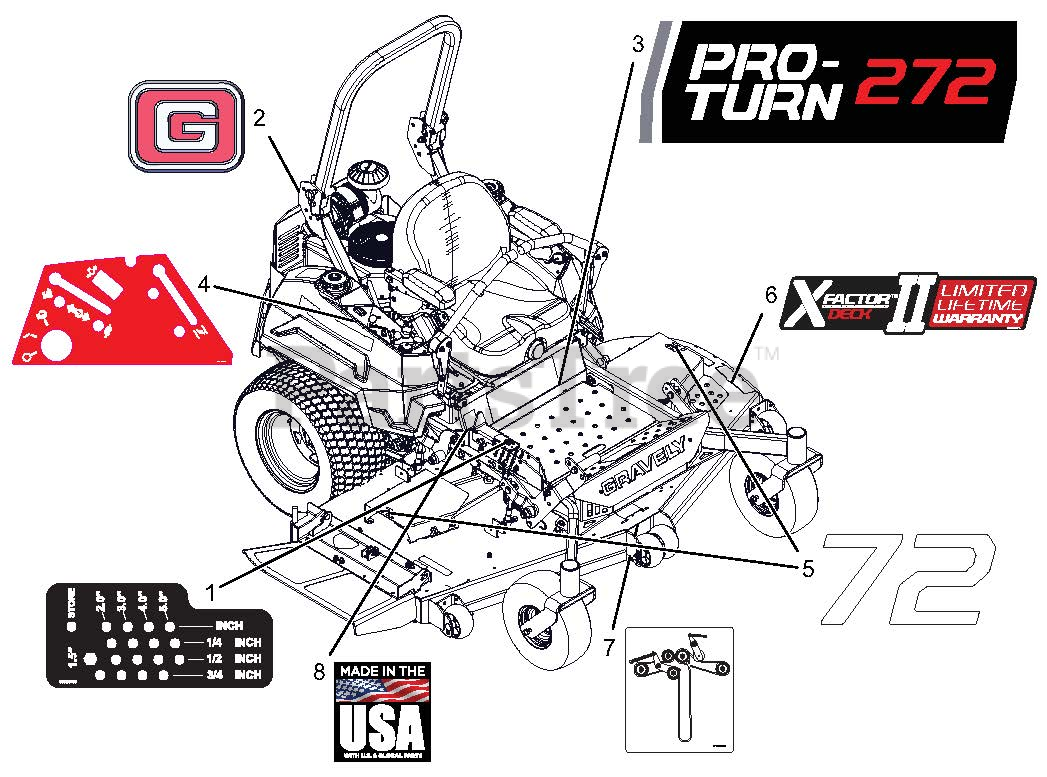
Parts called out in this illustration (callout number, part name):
1	DECAL, HEIGHT OF CUT
2	DECAL, GRAVELY BRAND
3	DECAL, PRO-TURN 272
4	DECAL, NON-EFI CONTROL PANEL
5	DECAL, 72"
6	DECAL, X-FACTOR DECK
7	DCL,BELT ROUTE-RH BK-SIDE IDLR
8	DECAL, MADE IN USA
